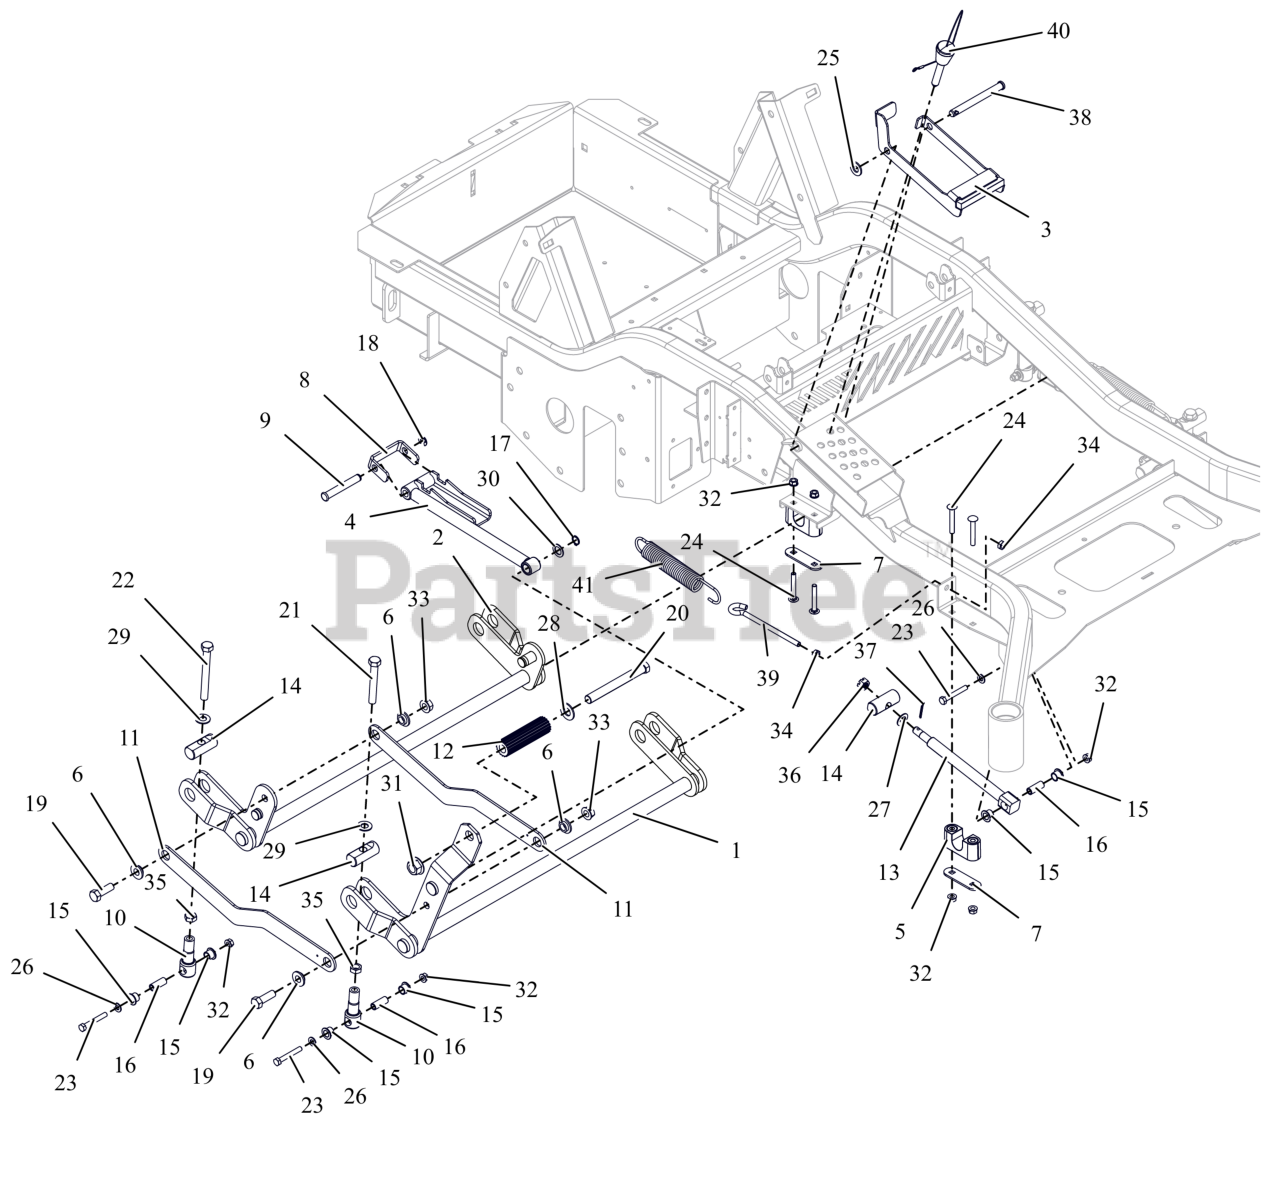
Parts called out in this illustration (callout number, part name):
1	WLDMT, FRONT DECK LIFT PIVOT
2	WLDMT, REAR DECK LIFT PIVOT
3	WLDMT, HOC TRANSFER LOCK (BLACK)
4	WLDMT, HOC LIFT ARM (BLACK)
5	ASM-BUSHING, DECK LIFT
6	BSHG-FLG .515X.750X.310X1.120
7	PLATE, BEARING SUPPORT
8	BRKT, HOC LINE
9	PIN, .499/.494 x 3.385 CLEVIS
10	LINK, DECK LIFT FORMED
11	LINK, DECK
12	ROD, FOOT PEDAL (BLACK)
13	DRAG,LINK-HD
14	PIN, DECK LIFT
15	BSHG, FLANGED .50X.625X.50X.062
16	SPCR, .31X.50X1.265
17	RG-RTNG-EXT .625X.050
18	RG-RTNG-EXT .500X.042 (E)
19	BLT,HEX .50-13X1.50 G5 ZCC
20	BLT, HEX .62-11X5.50 G5 FBP
21	BLT, HEX 0.5-13X3.5F GR5 ZCC
22	BLT, HEX .50-13X4.50F G8 ZCC
23	BLT, HEX .31-18X2.25 G5 ZCC
24	BLT, RHSSN.31-18X2.25 G5 ZCC
25	WSHR,FLT .531X1.062X.095 ZCC
26	WSHR,FLT .344X.688X.065 ZCC
27	WSHR, BLVL .505 X 1.000 X .073 ZCC
28	WSHRFLT 5/8SAE CARBHARD FBP
29	WSHR, FLT .557X1.040X.102 ZCC
30	WSHR, FLT .630X1.005X.062 ZCC
31	NUT,FLG-TOP LK .625-11 FBP
32	NUT,LK-CTR-FLG .31-18 GF ZCC
33	NUT-LK-CTR-FLG .500-13 GG ZCC
34	NUT-JAM .375-16 G2 ZCC
35	NUT-JAM .500-13 G2 ZCC
36	NUT-SL .50-13
37	PIN,CTR.12X1.25EXTPRSQCT ZC120
38	PIN, SLIC-.500X4.97X4.55 -ZC
39	BOLT,.38-16 X 5.25-.62 DIA EYE
40	PIN- MAGNETIC .50X2.70
41	SG-TENS .162X1.25X8.25 WLD 25
